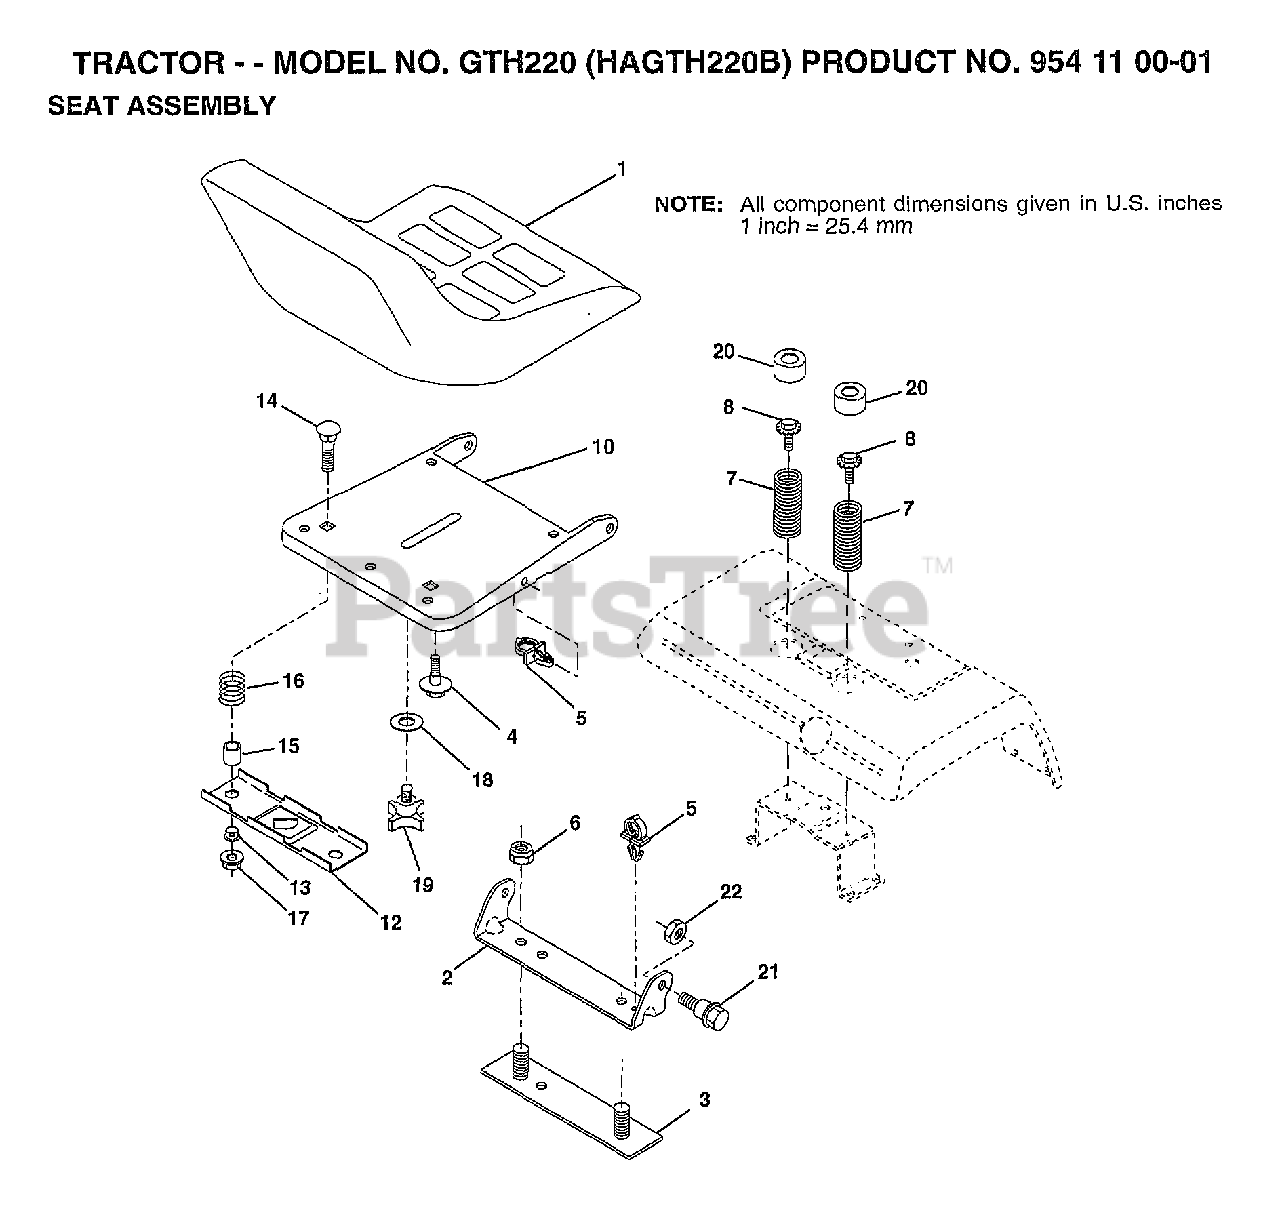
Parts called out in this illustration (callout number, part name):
1	SEAT V560 GRY/B
6	LOCKNUT
14	BOLT, CARRIAGE 1/4-20 X 1-1/2
18	WASHER 17/32 X 1-3/16 X 12 GA
22	LOCKNUT, CROWN 5/16-18
